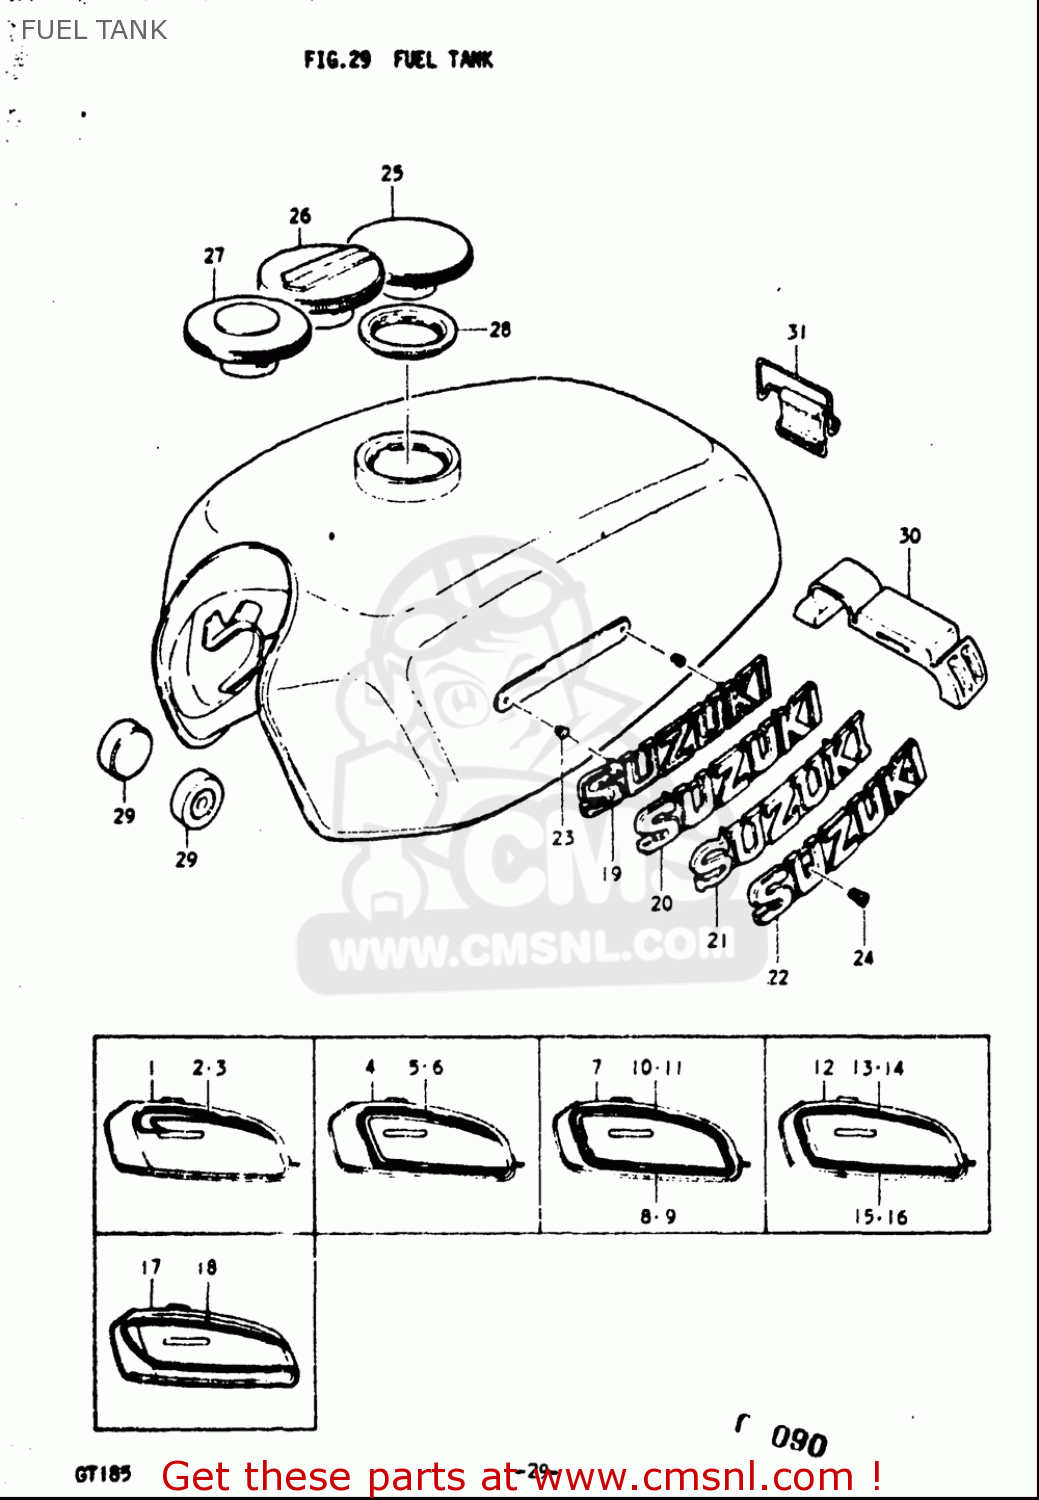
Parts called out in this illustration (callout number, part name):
22	EMBLEM,FUEL TANK
23	NUT
24	SCREW
27	CAP ASSY,FUEL TANK FILLER
28	GASKET (NAS)
29	CUSHION
30	CUSHION
31	BAND
